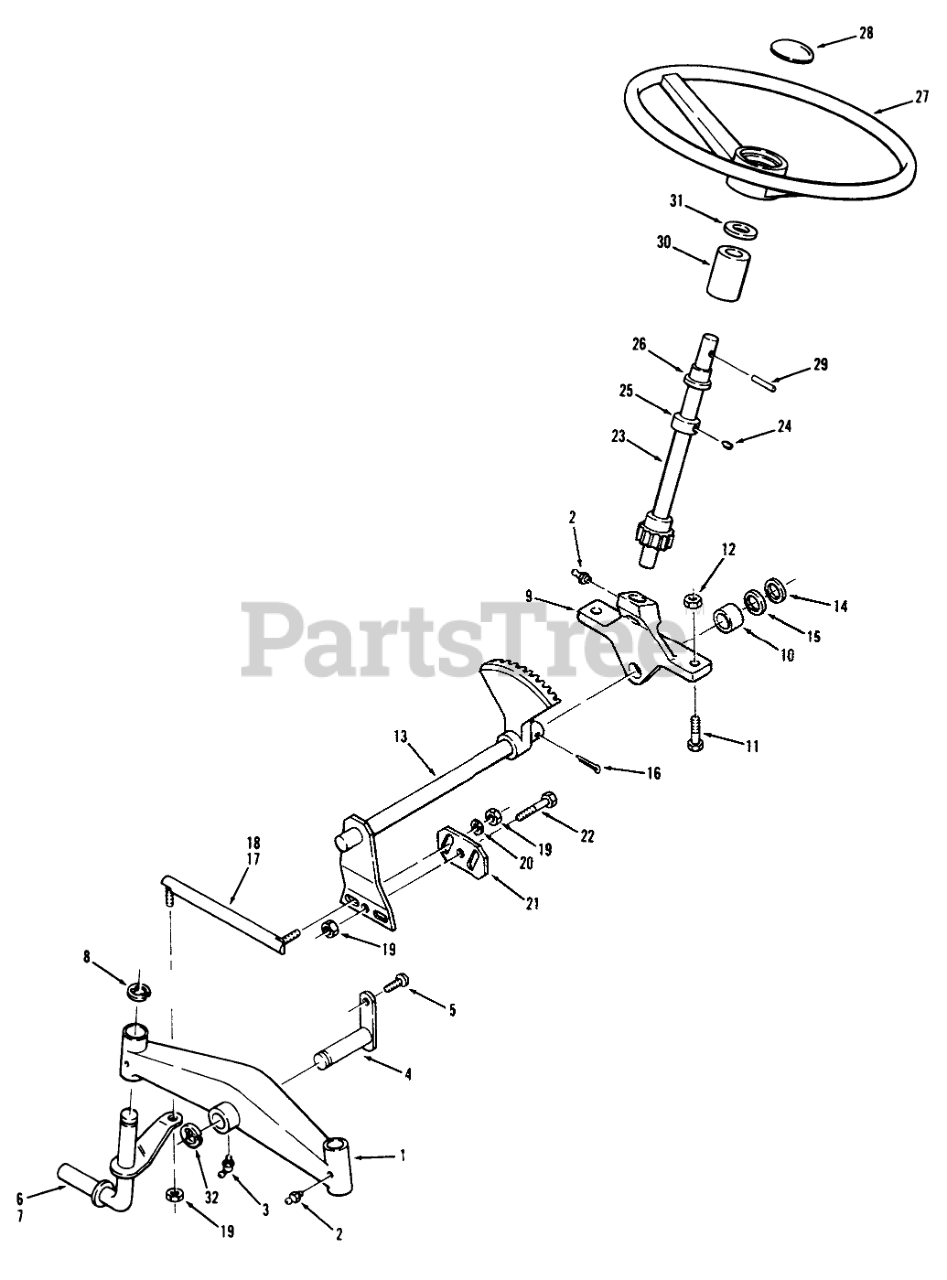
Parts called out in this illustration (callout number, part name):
1	Axle-Front
2	Zerk
3	FITTING-GREASE
4	Hex Nut
5	Bolt
6	Front Spindle RH
7	Front Spindle LH
8	Snap Ring
9	Support
10	BEARING-BRONZE
11	BOLT
12	Nut
13	Assy-Steering Shaft
14	WASHER-SHIM
15	WASHER
16	PIN-4
17	25LL JOINT ASSY R R
18	BALL JOINT ASSY L R
19	NUT-6
20	Washer
21	Hanger
22	H H C S
23	ASSY-STEER SHFT U R
24	SCREW-SET
25	Collar
26	BEARING
27	STEERING WH 13" PLAS
28	STEERING WHEEL INSE
29	Pin-Roll
30	Collar
31	WASHER-BOWED
32	E-RING
